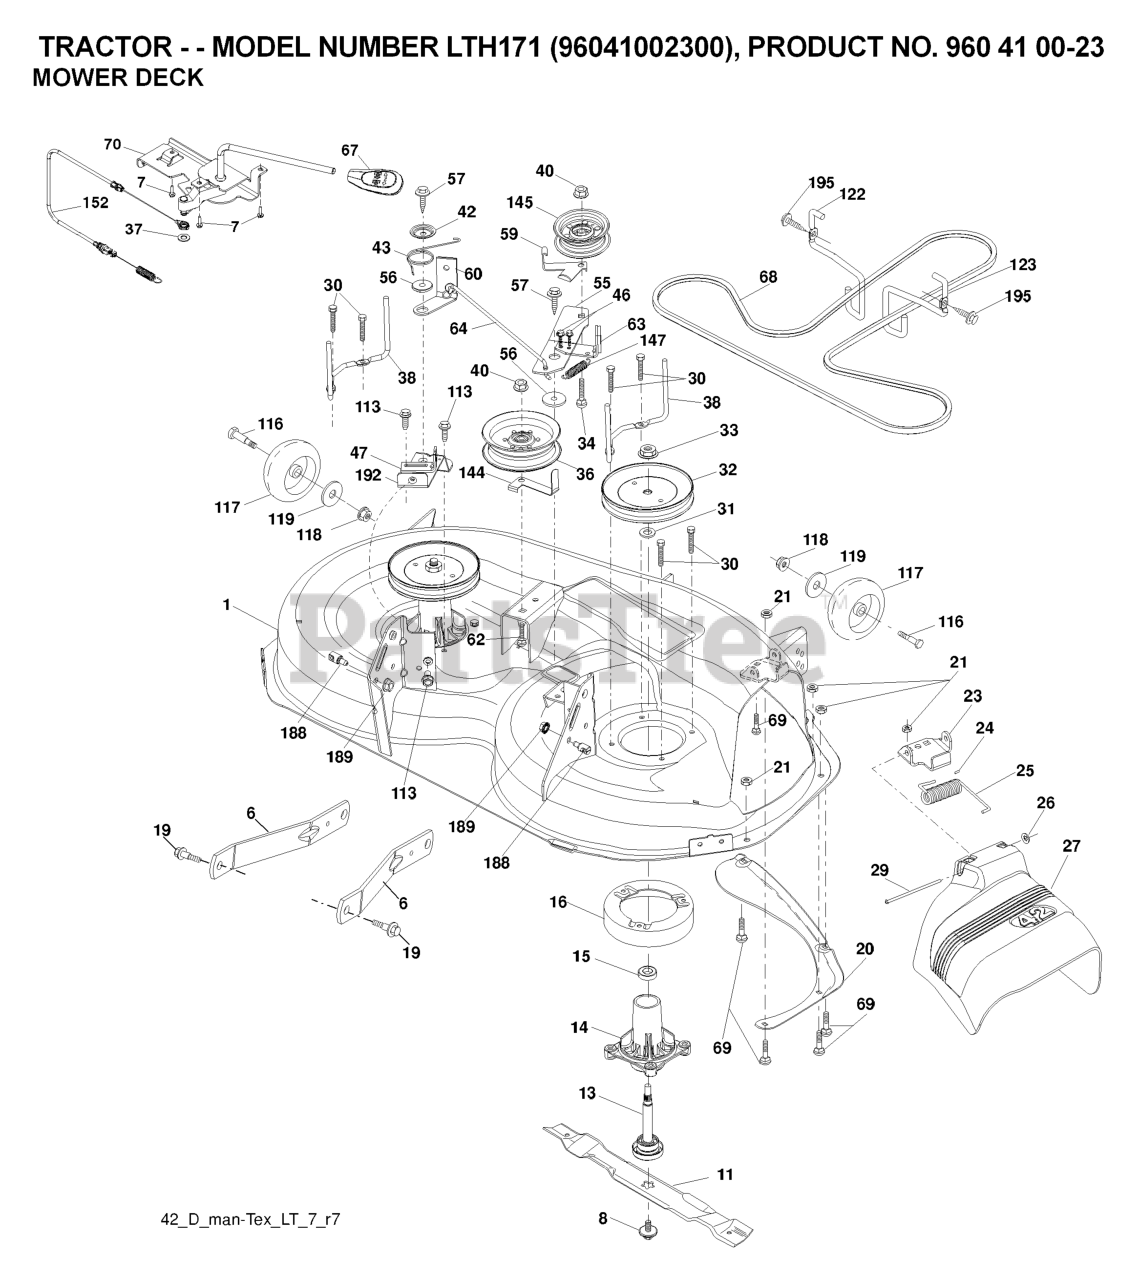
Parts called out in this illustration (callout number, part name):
6	ARM.SUSPENSION.MOWER.R
7	SCREW.#10 X 0.750.BOS
8	BOLT.WASHER.ASM.7/16-2
11	42" HI-LIFT BLADE
13	SHAFT.ASM.MDRL.N/GREASE.38
14	RP.HOUSING.MANDREL.4PT.
16	STRIPPER.MANDREL.ROUND.BLACK
19	BOLT.SHOULDER
20	BAFFLE.VORTEX
21	LOCKNUT
23	BRKT.DEFLECTOR.38"2005+
24	CAP-SLEEVE LT
25	SPRING.TORSION.DEFLECT
26	NUT PUSH M
27	SHIELD.DEFLECTOR.MOWER.42"BLAC
29	ROD.HINGE
30	SCREW, WASHER HEAD
31	WASHER.SPACER.MANDREL
32	PULLEY.MANDREL.5.438.PD
33	NUT.FLANGE.LOCK.TOP
34	BOLT.3/8-16X1.50
36	PULLEY.IDLER.2006
37	WASHER
38	KEEPER.BELT.LH.MANDREL
40	NUT LOCK FLG 3/8-16 UNC
42	SPRING.TORSION.BRAKE
43	SRPING.TORSION.RETAINE
46	SCREW.1/4-20X5/8
47	BRKT.CLUTCH.CABLE
56	SPACER.RETAINER
57	SCREW 3/8-16X1
59	GUARD, BELT
60	ARM BRAKE MOWER
63	ARM BRAKE MOWER
64	LINK BRAKE
67	HANDLE.CLUTCH.CABLE.LT
68	BELT.DECK.DRIVE.42"
69	BOLT
70	CLUTCH.ASM.MANUAL.LT.PRED
113	BOLT.5/16HEX.WHS.HD
116	BOLT M
117	WHEEL.GAGE.HALF.SPOKED
118	LOCKNUT
119	WASHER.5/16.FLAT.STE.STD.
122	KEEPER BELT ENGINE LH
123	KEEPER BELT RH
144	KEEPER.BELT.MOWER
145	PULLEY.IDLER.48"PRIMARY
147	RETURN SPRING
152	CLUTCH CABLE
188	STUD.FASTNER.W/ANTI-ROTATE
189	NUT LOCK HEX FLANGE 5/16-18
192	BRKT.BRAKE.STAND.LH.
195	SCREW, 3/8-16X3/4
